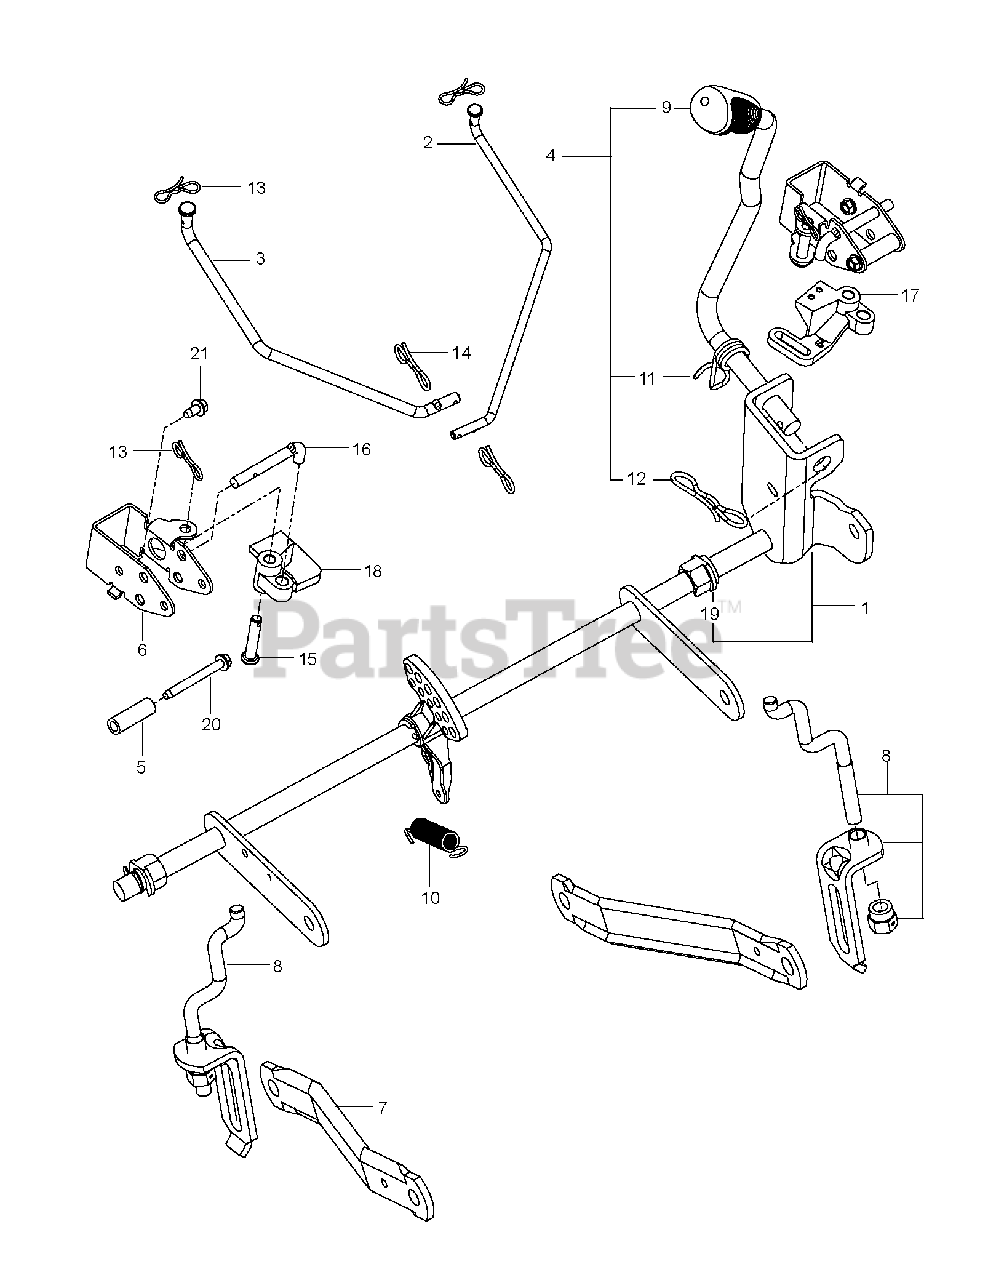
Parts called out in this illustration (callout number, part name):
1	SHAFT.ASM.RZ.DECK.LIFT.SRV
2	LINK.BRAKE.PARK.UPPER.LH
3	LINK.BRAKE.PARK.UPPER.RH
4	LIFT.LEVER.ASM.RZ.SERVICE
5	SPACER.334.ID.5.OD.1.5.L
6	BRACKET.BELLCRANK.PBRAKE X431
7	ARM.SUSPENSION.MOWER
8	LINK.ASM.RZ.LIFT.SERVICE
9	GRIP.HANDLE.LIFT.PVC.BLACK
10	RETURN.BRAKE.PARK.AUTO
11	SPRING.TORSION.LIFT.HANDLE
12	PIN.COTTER.7/16.BOW TI.
13	PIN COTTER;LOCKING;BOWTIE;1IN
14	PIN.COTTER.5/16.BOW TI
15	PIN.5.16X1.5
16	ROD.PUSH.BRAKE
17	BELLCRANK.LH
18	BELLCRANK.RH
19	PLASTIC NUT
20	SCREW THD;ROLL;1/4-20 X 2.25
21	SCREW THD;ROLL;1/4-20 X 2.25
